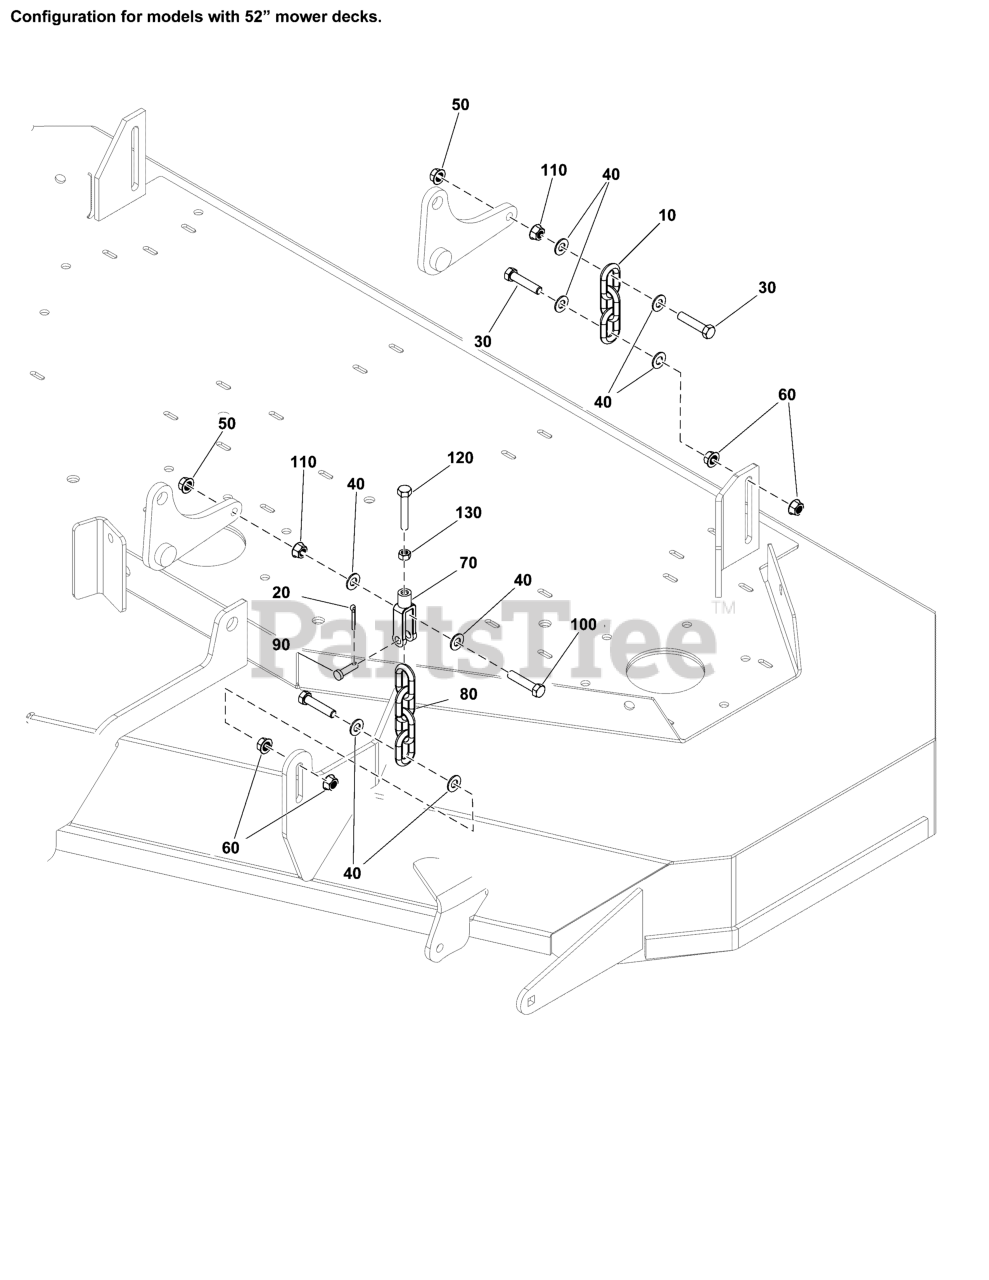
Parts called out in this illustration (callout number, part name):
10	CHAIN, 5/16" GD30, 3
20	PIN, COTTER, 3/32X.75
30	BOLT, 3/8-16 X 1-3/4"
50	NUT, 3/8-16 HEX NYLOCK
60	NUT, 3/8-16 HEX SERRA
70	CLEVIS, 5/16-18, 3/8
80	CHAIN, 5/16", 4 LINKS
90	PIN - CLEVIS
100	CAPSCREW, 3/8-16X2
110	NUT, 3/8-16 HEX JAM
120	BOLT, 5/16-18X2
130	NUT, 5/16-18 HEX JAM
